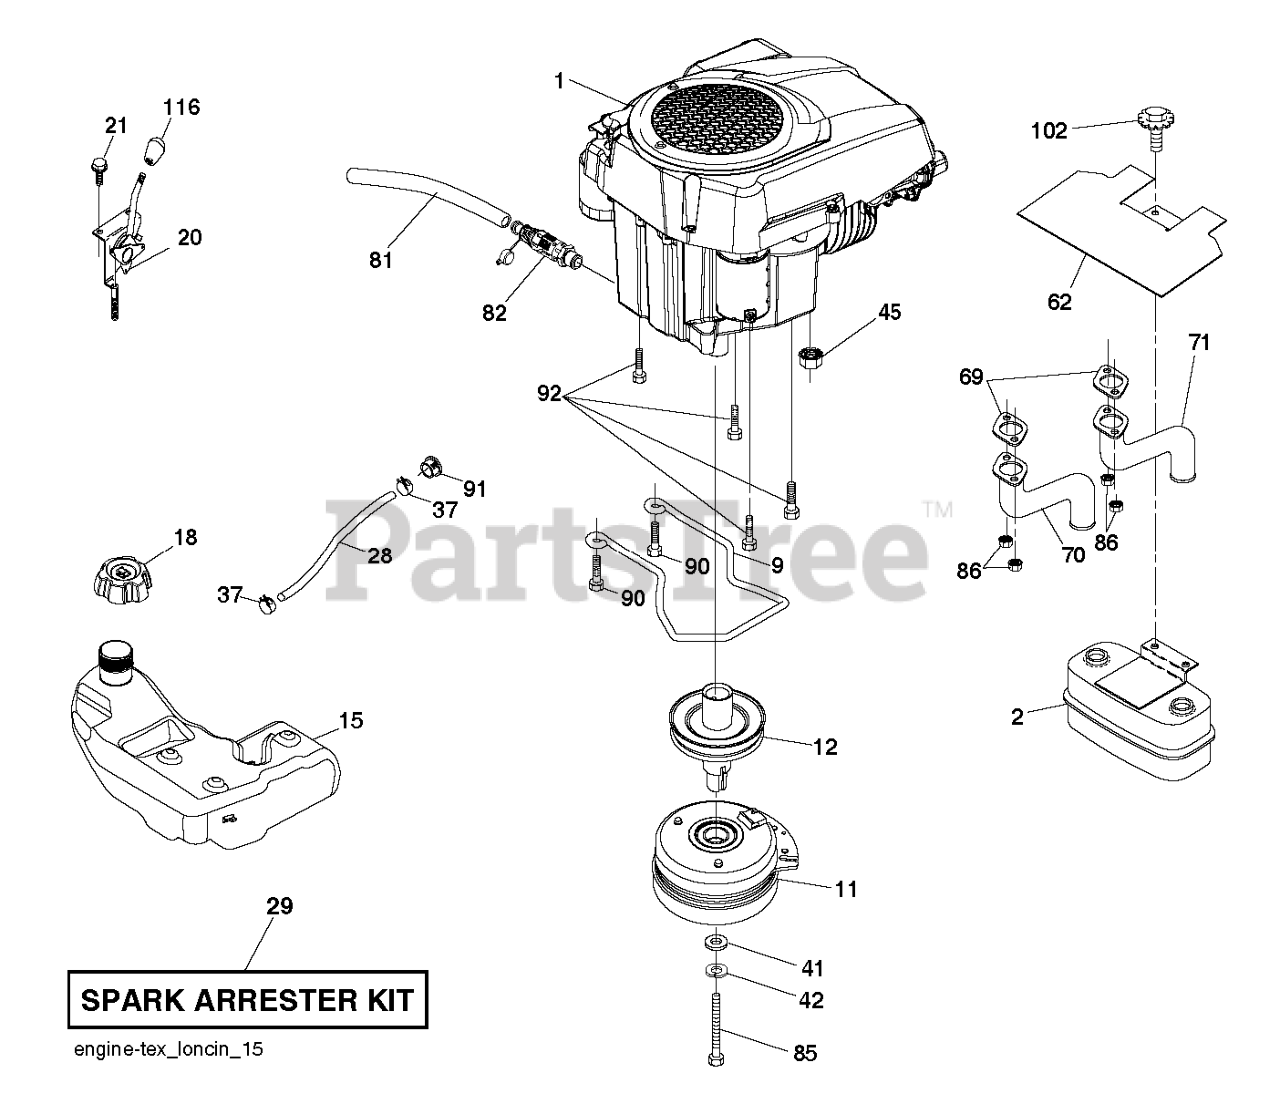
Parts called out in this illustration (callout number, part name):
2	MUFFLER.ASM.TWIN.MNTG.BRACKET
9	KEEPER.BELT.ENG.4.25"2.BLT.431
11	CLUTCH. 5.0 PD. 2.5 OFFSET
12	PULLEY.EXTENDED.SHAFT.GROUND
15	TANK.FUEL.4GAL
18	CAP.ASSY.FUEL.3".N-EPA.GRY.498
20	CONTROL.THROTTLE/CHOKE.PRO.45
28	LINE.FUEL.64"REAR.EMIS
29	KIT.SPARK ARRESTOR 794945 B&S
37	HOSE CLAMP
45	NUT HEXAGON WITH FLANGE, SERRA
62	SHIELD.HEAT.MUFFLER
81	TUBE, DRAIN OIL ASM.
82	VALUE.OIL.DRAIN
85	BOLT.HEX.7/16-20X5.GR5.GREEN
86	NUT.HEX.FLANGE.TOPLOCK
90	SCREW 3/8-16X1
91	BUSHING.1.375OD
92	SCREW 3/8-16X1
102	SCREW
116	KNOB - SHIFT
